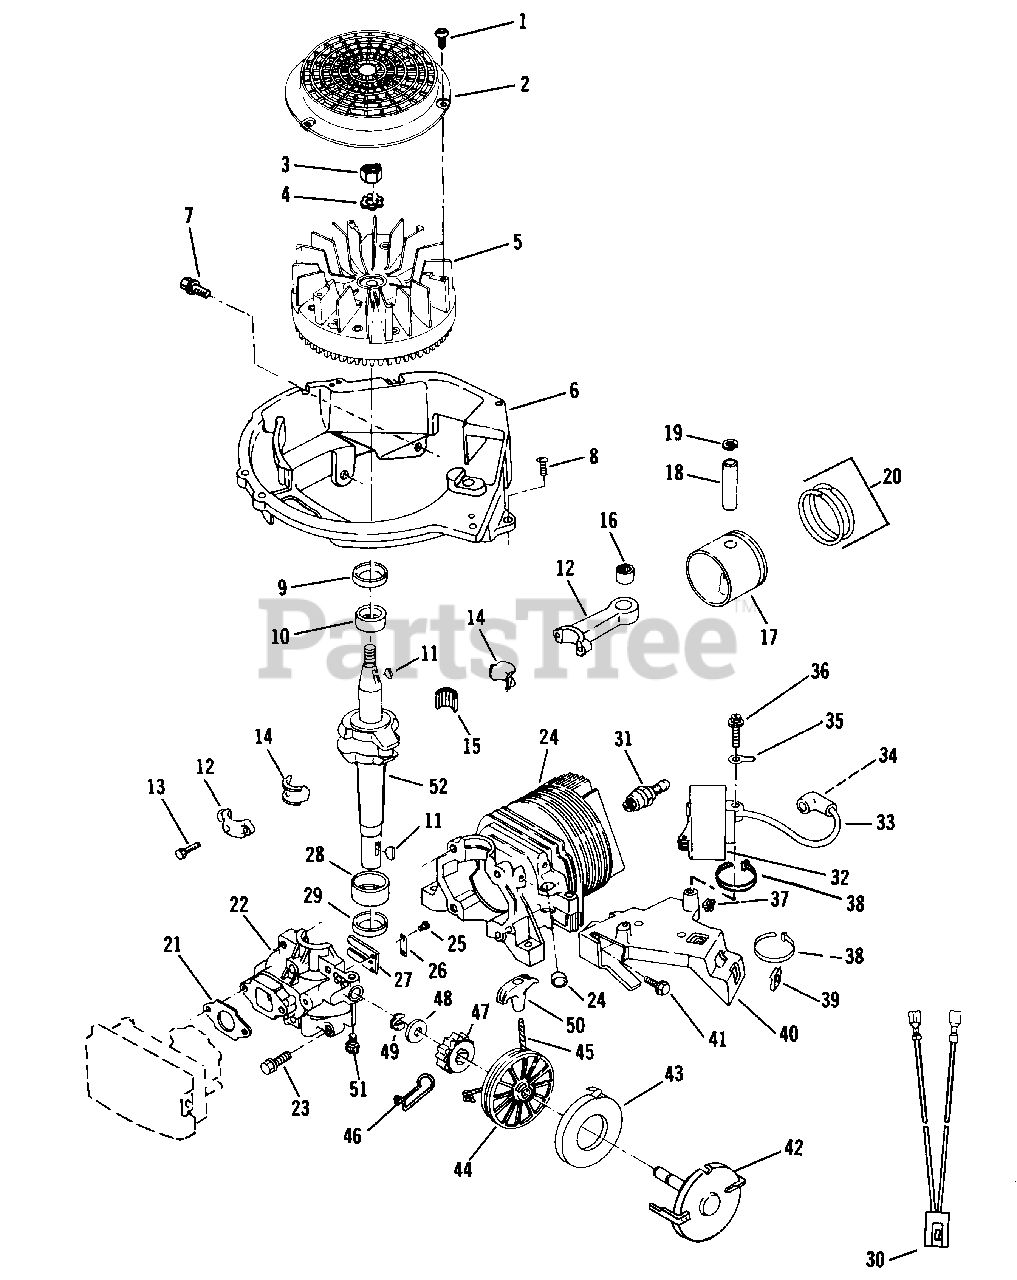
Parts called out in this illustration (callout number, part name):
2	Screen-Flywheel
3	Nut-Flywheel
4	Lockwasher
5	Flywheel Assembly
6	Shroud Base
8	Screw-Shd. Base to C.D. Brkt.
9	Oil Seal-Upper
10	Bearing-Main-Upper
11	Key-Flywheel
12	Conn. Rod Assembly
14	Liner Split
15	Needle Bearing Set
16	Bearing Assembly
17	Piston and Ring Set
18	Wrist Pin
19	Retaining Ring
20	Ring Set
21	Gasket-Carburetor to Crankcase Cover
22	Cylinder and Crankcase Cover Assembly
23	Screw-Cover to Crankcase
25	Screw-Reed to C'case Cover
26	Plate-Reed Hold Down
28	Bearing-Main-Lower
29	Oil Seal-Lower
30	Wire Harness-Engine
31	Spark Plug
32	C.D. Ignition Module and Lead Assembly
33	High Tension Lead
34	Spring Terminal
35	Terminal-Ground Lead
36	Screw-C.D. Mounting
37	Grommet-C.D. Bracket
38	Tie Strap
39	Clip-"U"
40	Bracket-Ignition Mounting
41	Screw
42	Spring Cup and Pin Assembly
43	Spring and Retainer Assembly
46	Spring-Drag
49	Retainer
50	Handle-Starter
51	Set Screw-Starter Assembly
52	Crankshaft
